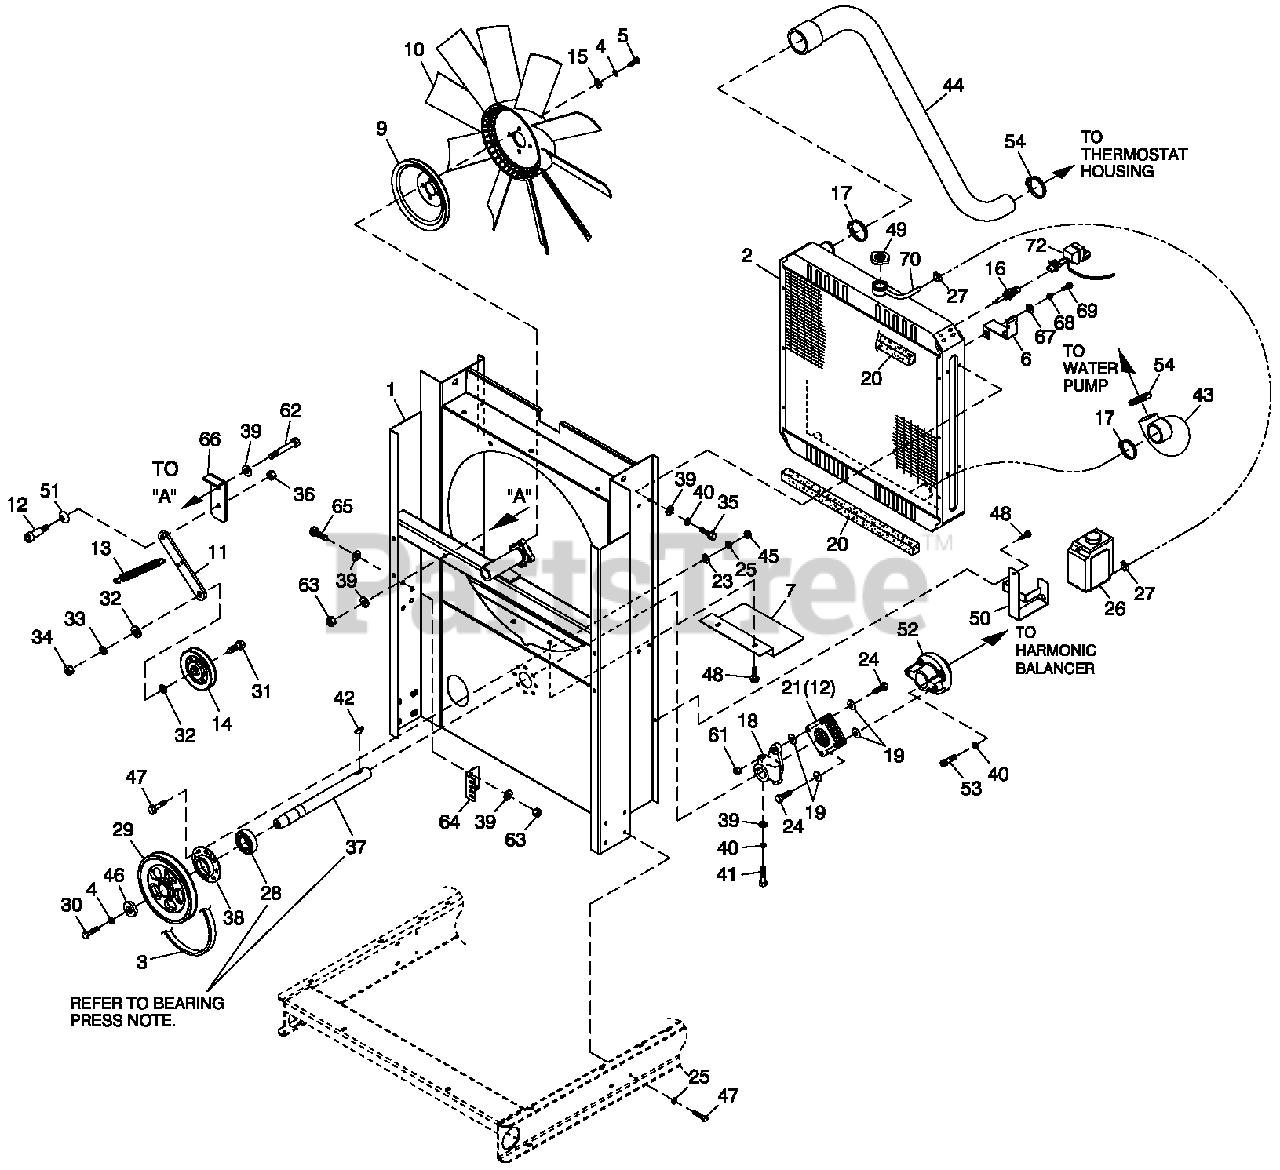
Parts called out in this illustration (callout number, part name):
1	WELDMENT RADIATOR SUPPORT C2
2	RADIATOR 598 X 568 X 49,CPL LH
3	V-BELT A58 (60INO.C.) DDC S60
4	WASHER LOCKM10
5	SCREW HHCM10-1.5X30G10.9
6	BRACKET, SIGNALCONDITIONER(USED ONLYWITHQTA PRODUCT)
7	SHIELD RADIATOR C4
9	PULLEY FAN V-GROOVE 9'
10	FAN COOL 22' DIA 10 BLADE LH
11	FLATTENSIONER ARM
12	SHOULDERBOLT 3/8 X 1/2'
13	SPRING TENSION CPL
14	PULLEY V- BELT 4" FLANGED
15	WASHERFLAT 3/8-M10ZINC
16	PROBE COOLANT LEVEL 3/8NPTF
17	CLAMP HOSE#281.32-2.25
18	HUB FLEX PLATE
19	WASHERFLEX (THIN)
20	TAPE FOAM 1X 1 (26.75' LG)
21	DISKFLEX
23	WASHERFLAT 1/4-M6 ZINC
24	SCREW HHC 5/16-24X 1.124
25	WASHERLOCK M6-1/4
26	TANK COOLANT RECOVERY
27	CLAM P HOS E BAND 1/4
28	BEARNG #6205 2NSE C3 E SRI2 S
29	PULLEY6.5' DIAMACHNED
30	SCREW HHC M10-1.5X30 G8.8
31	SCREW HHC 1/2-13X2" G8
32	WASHERFLAT 1/2ZINC
33	WASHERLOCK 1/2
34	NUT HEX 1/2-13 STEEL
35	SCREW HHFC M8-1.25X 20 W/M6
36	NUT HEX LOCK 5/16-18 NY INS SS
37	SHAFT FAN DRIVE
38	RETAINER BEARING
39	WASHERFLAT 5/16-M8ZINC
40	WASHERLOCK M8-5/16
41	SCREW HHC M8-1.25X45 C8.8
42	KEY WOODRUFF 4 X19D
43	HOSE RADIATOR LOWERFRONT
44	HOSE RADIATOR UPPERFRONT
45	NUT HEX M6X1.0G8YELCHR
46	SPACER.5X1.5X 25 STL/ZINC
47	SCREW HHFC M6-1.0X 20G8.8
48	SCREW THF M6-1 X 16 N WAZ/JS
49	CAP RADIATOR 13 PS I
50	BRACKET COOLANT TANK
51	WASHER BEL LEV LLE .75X.38X028
52	COUPLING FLEX HUB MACHINED
53	SCREW SHC M8-125 X30G 12.9
54	CLAMP HOSE#24B1.06-2.00
61	NUT HEX LOCK 5/16-24 NY INS
62	SCREW HHC M8-1.25X75 C8.8
63	NUT HEX LOCK M8-1.25 NY INS
64	BRACKET TENSIONER SPRING
65	SCREW HHC M8-1.25X20 C8.8
66	TENSIONER ARM SUPPORT BENT 90
67	WASHERFLAT 5/16-M8ZINC (USED ONLYWITH QTA PRODUCT)
68	WASHERLOCK M8-5/16(USED ONLY WITH QTAPRODUCT)
69	SCREW HHFC M8-1.25X20W/M6 (USED ONLYWITHQTA PRODUCT)
70	HOSE 9/32 ID (60" LG)
72	ASSY PCB LCLSENSOR (USE WITHI/N 16, P/N 0H1827ONLY)
